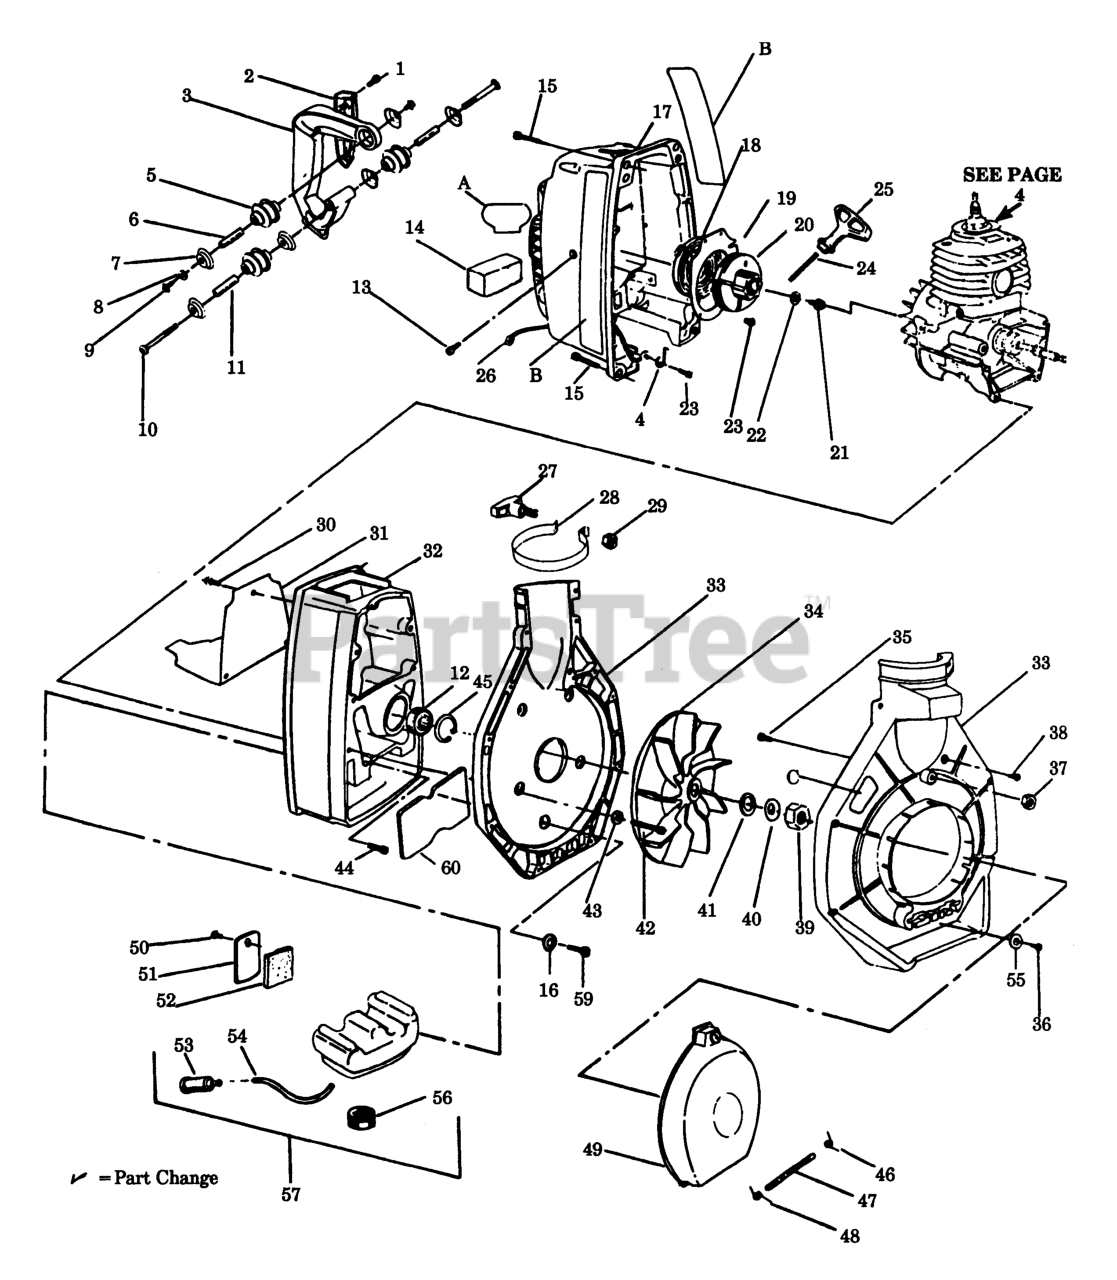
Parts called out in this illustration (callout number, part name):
1	SCREW-10-14X5/8 PHIL.FI
2	COVER-HANDLE (BLACK)
3	ASSY-HANDLE W/"D" RING
4	WIRE-STATIC GROUND
5	Handle Isolator
6	SPACER REAR MOUNT
7	CUP-ISOLATOR
8	WASHER (#8)
9	SCREW-8-32 X 7/16 BIND
12	Ball Bearing (Shroud)
14	AIR FILTER
15	SCREW 10-24 X 1.00 SEMS
17	Fan Housing
18	SPRING-STARTER
19	BAFFLE-AIR
23	SCREW-10-14X3/8 TRI-LOB
26	Ground Wire
27	KIT "T" HANDLE
28	CLAMP-BLOWER TUBE
30	SCREW-10-24 X 5/16 FIL.
31	DEFLECTOR-HEAT
32	Shroud
33	Blower Hsg. Kit
35	SCREW-10-24 X .88
36	SCREW-10-16X3/4 HI LO
38	SCREW
39	NUT-IMPELLAR
40	WASHER CONICAL
41	WASHER
42	SCREW-1/4-20 X 3/4 PAN
43	WASHER-FLAT (1/4")
44	SCREW-10-24 X 5/8 FILL
46	SPRING-TORSION (RIGHT)
48	SPRING-TORSION (LEFT)
49	ASSY-INLET DOOR
50	SCREW-1/4-20 X 1/2
51	RETAINER-FUEL TANK
52	FOAM-FUEL TANK
53	ASSY-FUEL PICK-UP
54	HOSE. FUEL
56	ASSY-FUEL CAP W/RETAINER
57	Fuel Tank Ass'y.
59	SCREW-10-24 X 5/8
60	SHIELD-FUEL TANK
A	Instruction Decal
B	Fan Housing Decal (Left & Right) - Model 22HB
B	Fan Housing Decal (Left & Right) - Model 28HBV
C	Blower/Vac Warning Decal
